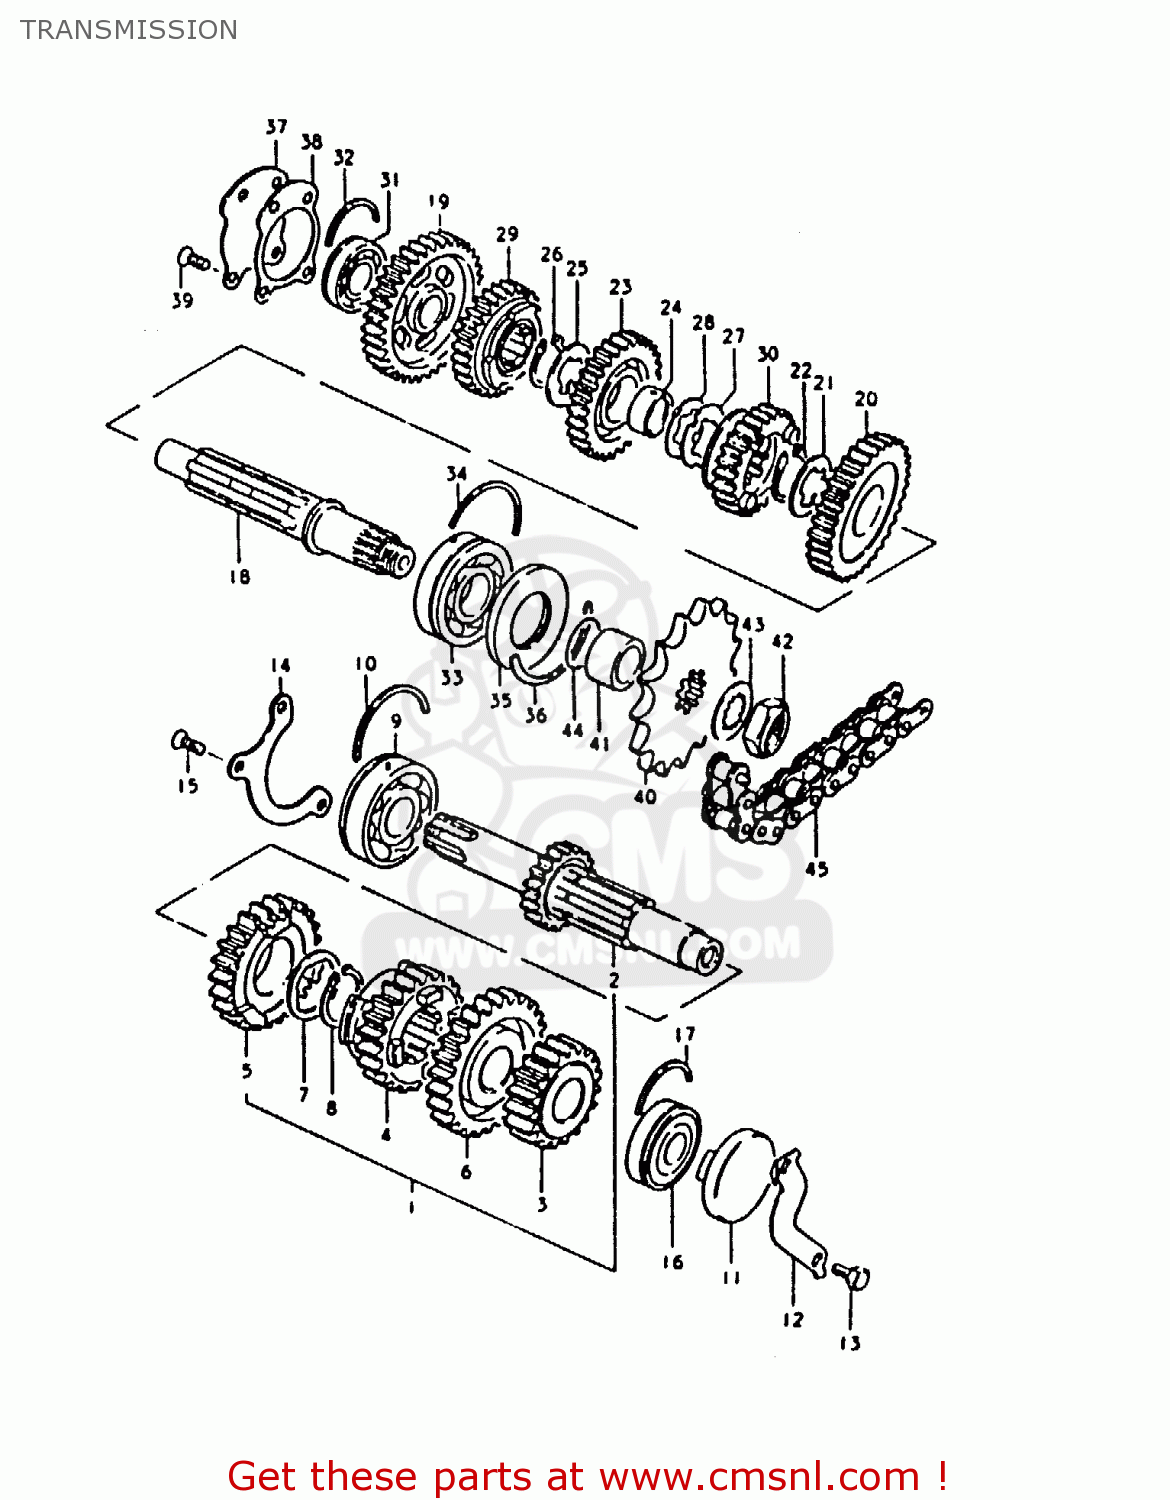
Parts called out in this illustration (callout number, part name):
1	SHAFT,COUNTER
2	SHAFT,COUNTER
3	GEAR,SECOND DRIVE
4	GEAR,THIRD DRIVE
5	GEAR,FOURTH DRIVE
6	GEAR,FIFTH DRIVE
7	WASHER,LOCK
8	CIRCLIP
9	BEARING(25X62X17)
10	C-RING
11	PLUG
12	RETAINER,CL PUSH ROD OIL SEAL
13	BOLT
14	RETAINER,CNTR SHAFT BEARING
15	SCREW
16	BEARING(20X47X14)
17	C RING
18	SHAFT,DRIVE
19	GEAR,FIRST DRIVEN
20	GEAR,SECOND DRIVEN
21	WASHER,LOCK
22	CIRCLIP
23	GEAR,THIRD DRIVEN
24	BUSH,3RD DRIVEN GEAR
25	WASHER,LOCK
26	CIRCLIP
27	WASHER,LOCK
28	WASHER
29	GEAR,FOURTH DRIVEN
30	GEAR,FIFTH DRIVEN
31	BEARING
32	C RING
33	BEARING(25X62X17)
34	C-RING
35	SEAL,OIL(32X62X7)
36	C RING
37	PLATE,DRIVE SHAFT
38	GASKET,DRIVESHAFT PLATE (MCA)
39	SCREW
40	SPROCKET,ENGINE
41	SPACER(25X32X18.6)
42	NUT
43	WASHER
44	O RING(D:1,ID:24.5)
45	CHAIN ASSEMBLY,DRIVE
